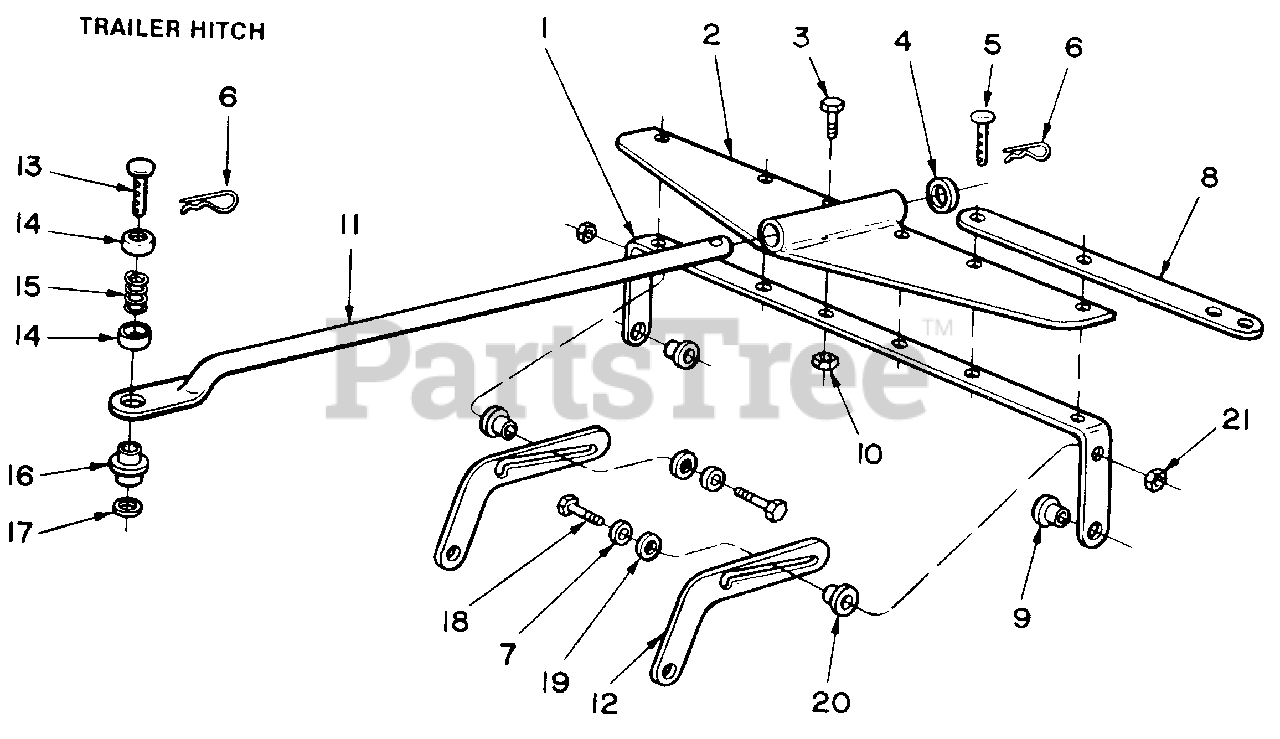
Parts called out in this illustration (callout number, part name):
1	Bridge
2	Tow Bar Plate Ass'y.
3	Bolt 5/16 x 18 x 1*
4	Washer
5	Clevis Pin
6	Cotter Pin
7	Washer- Special
8	Outrigger Bar
9	Spacer Bushing
10	Nut 5/16-18*
11	Tow Bar Ass'y.
12	Transport Brkt.
13	Clevis Pin
14	Spring Cup
15	Spring
16	Bushing
17	Washer 11/32 x 7/8*
18	Shoulder Bolt
19	Washer
20	Spacer
21	Hex L-Nut 1/4- 20*
